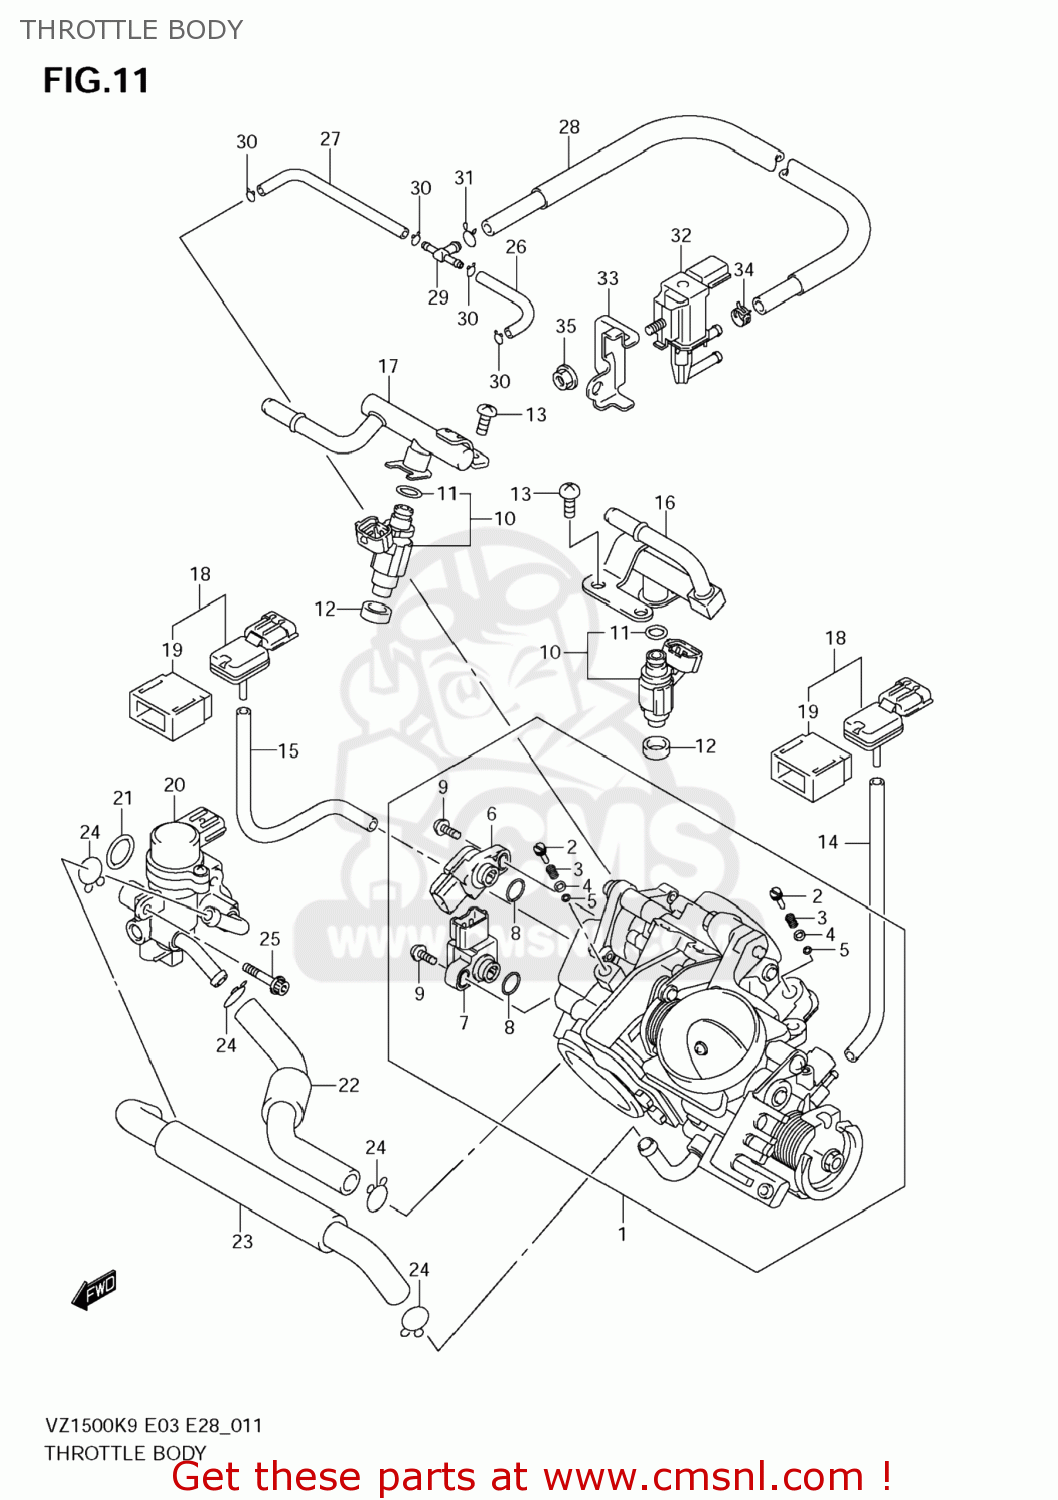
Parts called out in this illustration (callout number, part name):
1	BODY ASSY,THROTTLE
2	SCREW
3	SPRING,THROTTLE SCREW
4	WASHER
5	O RING,PILOT AIR SCREW
6	SENSOR ASSY
7	SENSOR ASSY
8	O RING
9	SCREW
10	INJECTOR ASSY
11	O RING
12	SEAL
13	SCREW
14	HOSE
15	HOSE
16	PIPE ASSY,DELIVERY
17	PIPE ASSY,DELIVERY
18	SENSOR,PRESSURE
19	HOLDER
20	VALVE,ISC
21	O RING(D:2.5,ID:13.8)
22	HOSE,ISC VALVE,R
23	HOSE,ISC VALVE,L
24	CLIP
25	BOLT
26	HOSE
27	HOSE
28	HOSE
29	NIPPLE
30	CLIP
31	CLIP
32	VALVE,CANISTER PURGE
33	BRACKET,PURGE VALVE
34	CLIP
35	NUT
